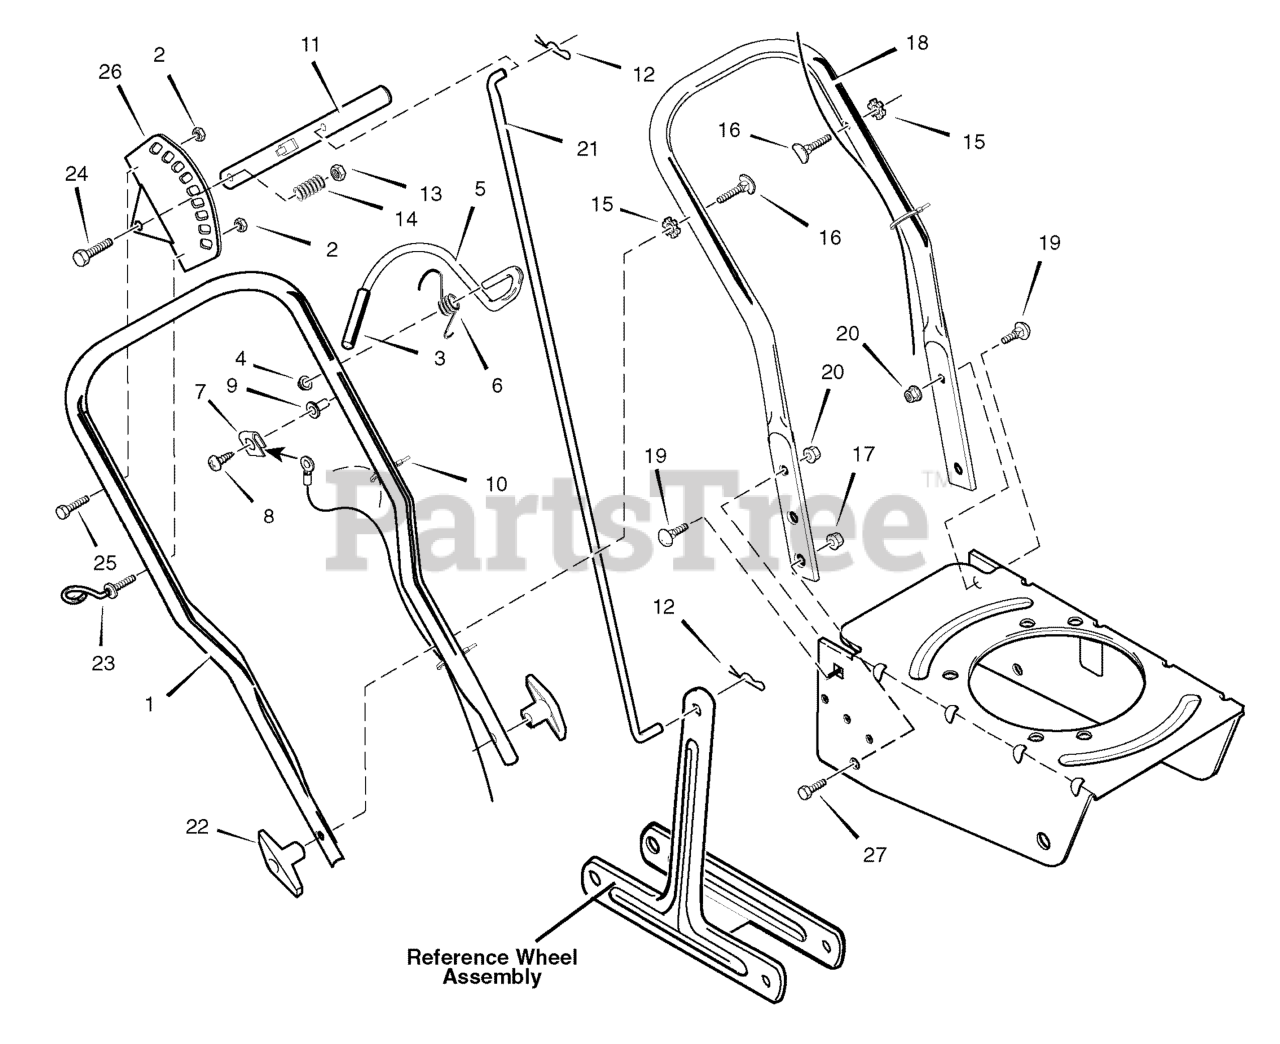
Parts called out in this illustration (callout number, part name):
1	HANDLE, Upper
2	NUT, 1/4-20
3	CAP, Operator Control
4	NUT, Push On
5	BAIL, Operator Control
6	SPRING, Torsion
7	CLIP, Grounding
8	SCREW, #6x.50
9	INSULATOR, Operator Control
10	CABLE TIE
11	HANDLE, Depth
12	HAIR PIN
13	NUT, 5/16-18
14	SPRING, Compression
16	BOLT, 5/16-18 x .75
17	NUT, 5/16-18
18	HANDLE, LOWER
19	BOLT, 5/16-18 x .75
20	NUT 5/16-18
21	ROD, Control
22	WING KNOB 5/16-18
23	ROPE GUIDE
25	SCREW, 1/4-20 x 1.25
26	BRACKET, Adjustment Quadrant
27	BOLT, 5/16-18 x 2
